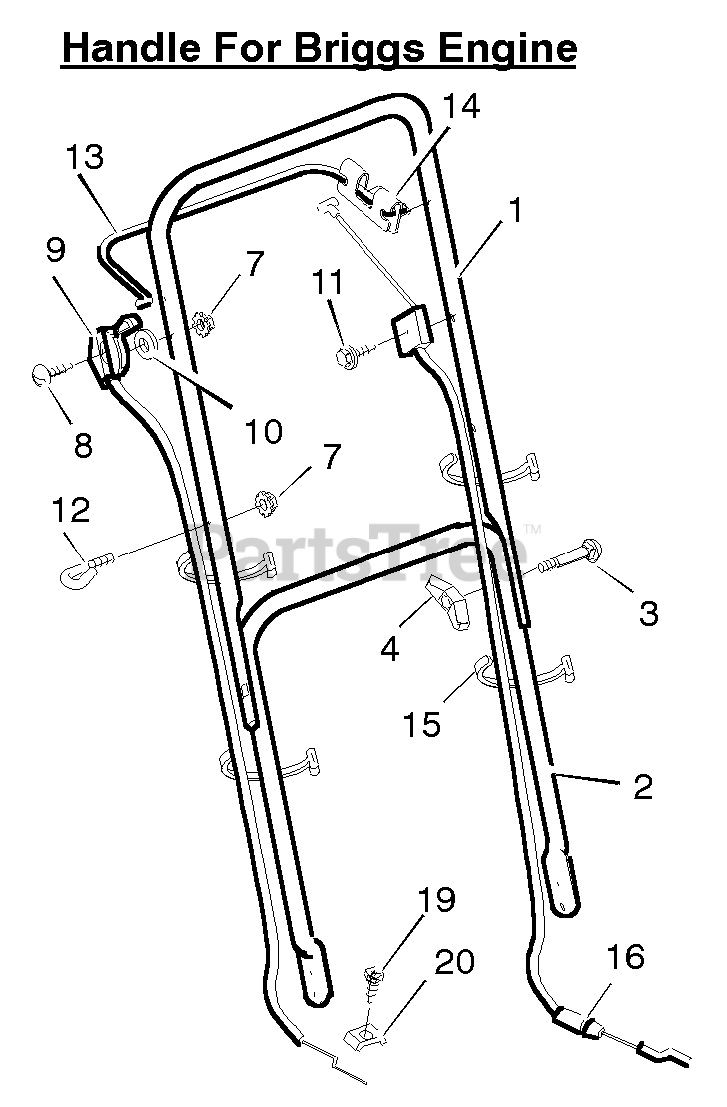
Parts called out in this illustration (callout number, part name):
1	Handle, Upper-Straight (Black)
2	Handle, Lower (Black)
4	Knob, Plastic
7	Locknut
9	Throttle Control
10	Washer
12	GUIDE, ROPE
13	Engine Stop Lever-Straight
14	Bracket, Stop Lever
15	Fastener, Cable
16	Engine Stop Cable
